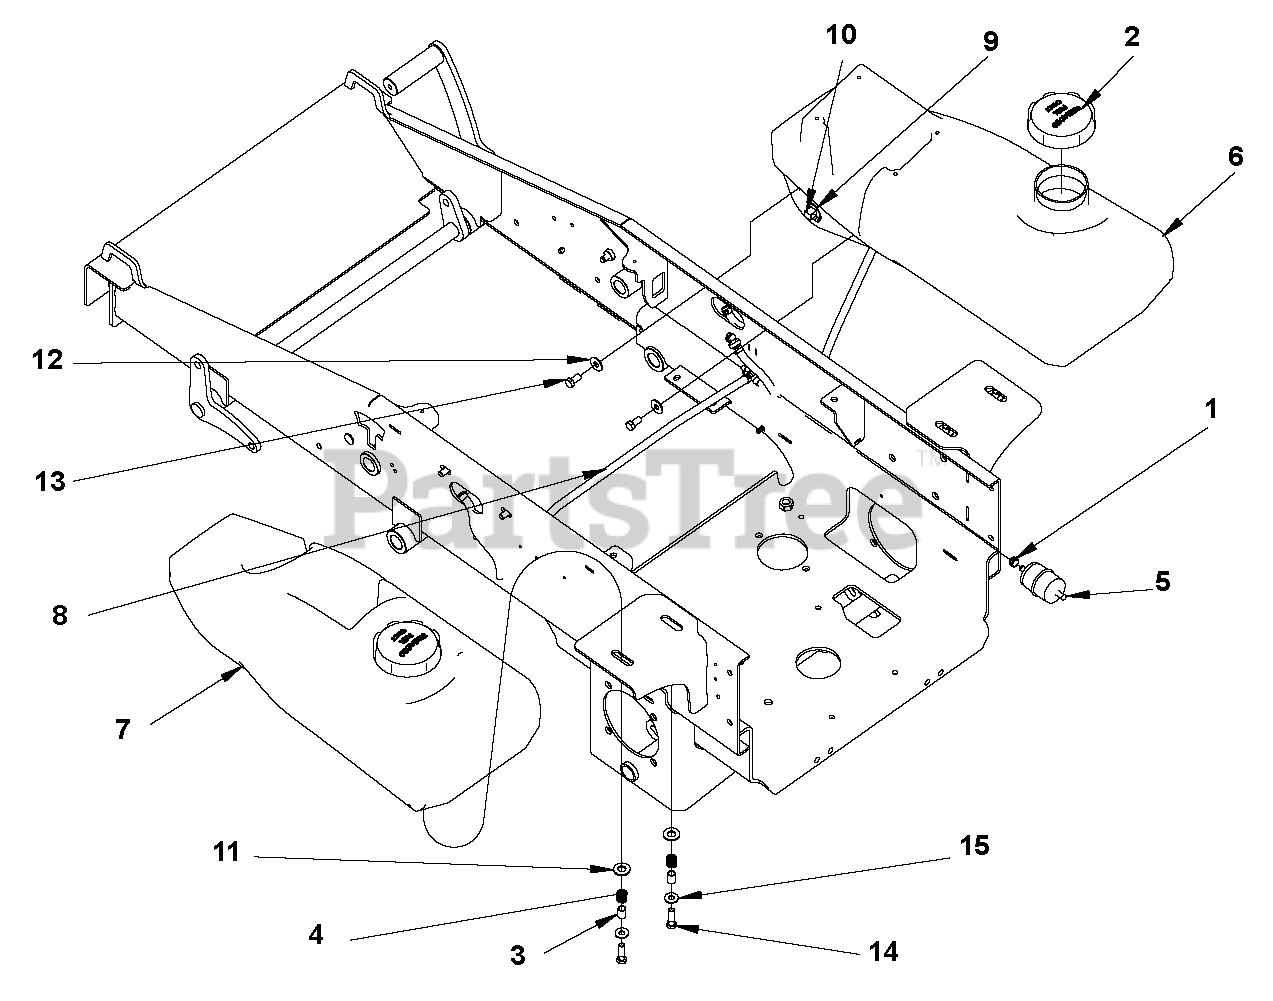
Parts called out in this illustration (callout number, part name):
1	Clamp, 1/2 Spring Hose
2	Fuel Cap
3	Spacer, Gas Tank Attachment
4	Spring, Commpression .660 x .067 x .625
5	Fuel Filter
6	Tank, RH Midmount Blank w/Cap
7	Tank, LH Midmount Blank w/Cap
8	Assembly, Fuel Line w/Checkvalves
9	Grommet, Tank Fitting Rubber
10	Fitting, 90 Degree
11	Washer, .500 x 1.00 x .105 Flat
12	Washer, .375 REG Flat
13	Bolt, 3/8-16 x .750 Hex Grade 5
14	Bolt, 3/8-16 x 1.25 Hex Grade 5
15	Washer, .313 REG Flat
